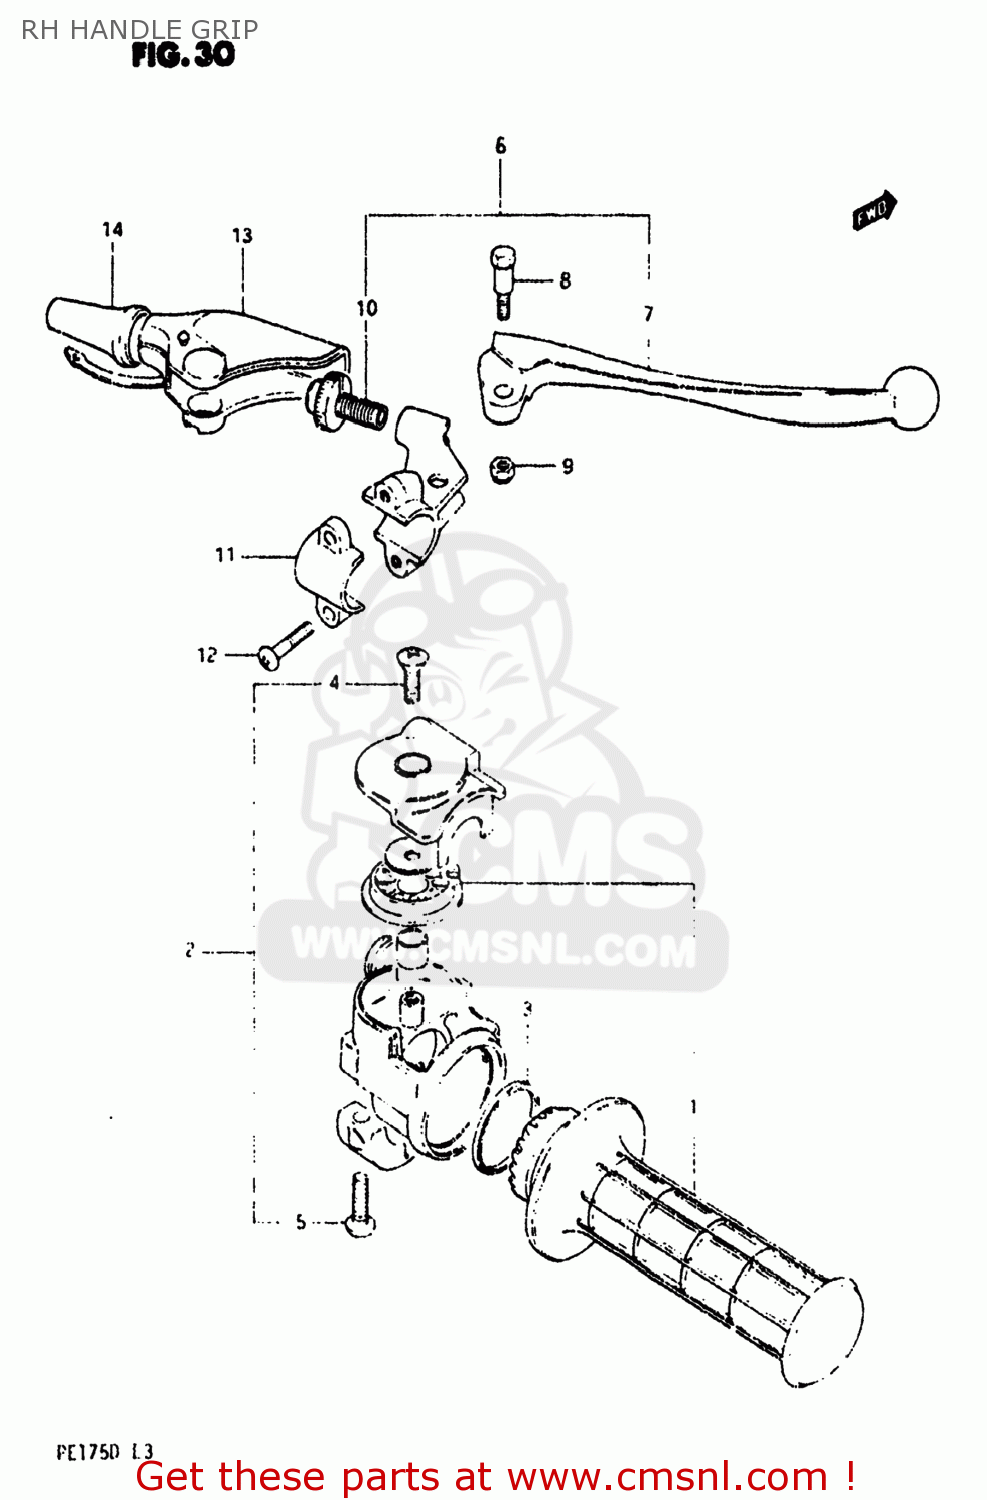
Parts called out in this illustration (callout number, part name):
1	GRIP SET,THROTTLE
2	CASE ASSY,THROTTLE
3	V-RING,THROTTLE GRIP
4	SCREW
5	SCREW 5X20
6	LEVER ASSEMBLY,BRAKE
7	LEVER,BRAKE
8	BOLT,LEVER
9	NUT 6MM
10	ADJUSTER,CABLE
11	BRACKET,LEVER
12	SCREW
13	COVER,BRAKE LEVER
14	BOOT,CLUTCH CABLE
